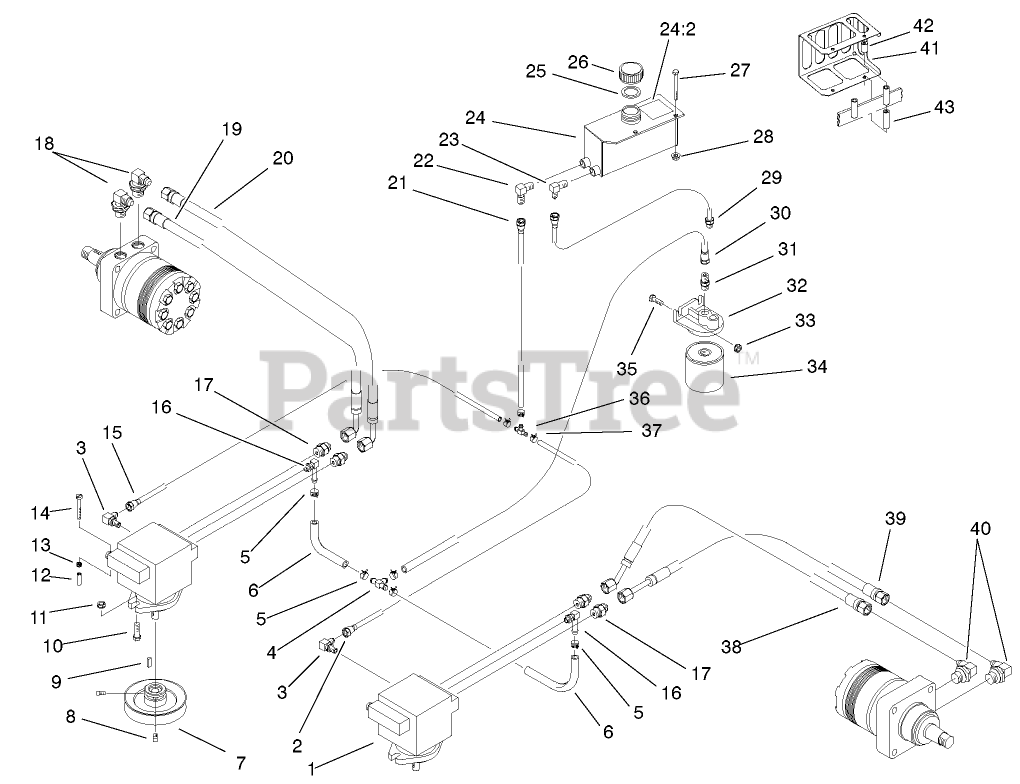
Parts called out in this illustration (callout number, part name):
1	PUMP-HYDRAULIC
2	HOSE ASM
3	FITTING-90 DEG
4	FITTING-TEE, HOSE
5	CLAMP-HOSE
7	PULLEY
8	SCREW-SET
10	SCREW-HH
11	NUT-HHF, WHIZ
12	GRIP-VALVE, DUMP
13	NUT-LOCK, NI
15	HOSE ASM
16	FITTING
17	FITTING-STRAIGHT
18	FITTING-HYD, 90 DEG
19	HOSE-FRONT
20	HOSE-REAR
22	FITTING-ELBOW
23	FITTING-ELBOW
24	HYDRAULIC TANK ASM
24:2	DECAL-HOT SURFACE
25	GASKET-CAP, TANK
27	SCREW-HH
28	NUT-HF
31	FITTING-STRAIGHT
32	HEAD-FILTER
33	NUT-HF
34	FILTER-OIL, HYD
34	FILTER-OIL, HYD (WINTER)
35	SCREW-HH
36	FITTING-TEE, HOSE
37	CLAMP-HOSE
38	HOSE-REAR
39	HOSE-LH
40	FITTING-90 DEG
41	SHIELD-HEAT, HYDRO RES
42	SPACER
43	SPACER
